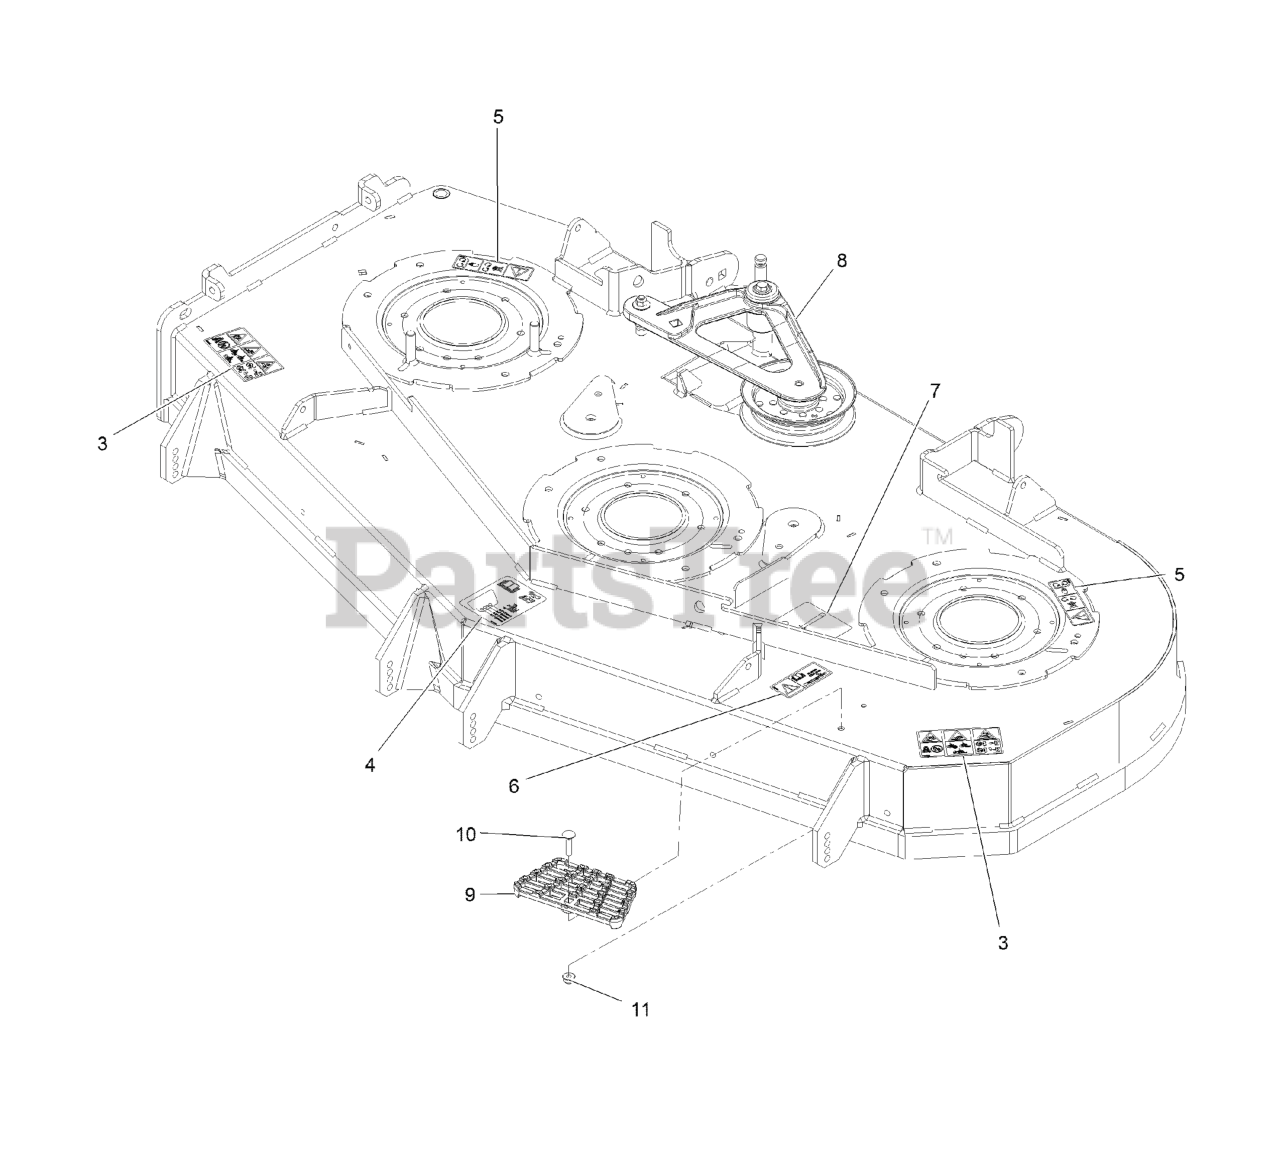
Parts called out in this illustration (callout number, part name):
3	DECAL-DANGER THROWN OBJECTS
4	DECAL-ROLLER, ANTI-SCALP
5	DECAL-COVER, MISSING
6	DECAL-TORQUE, BOLT
7	DECAL-BELT ROUTING
8	DECK IDLER ASM
9	STEP-DECK
10	Bolt-Carriage 5/16-18 X 1 1/4
11	NUT-HF, NI
